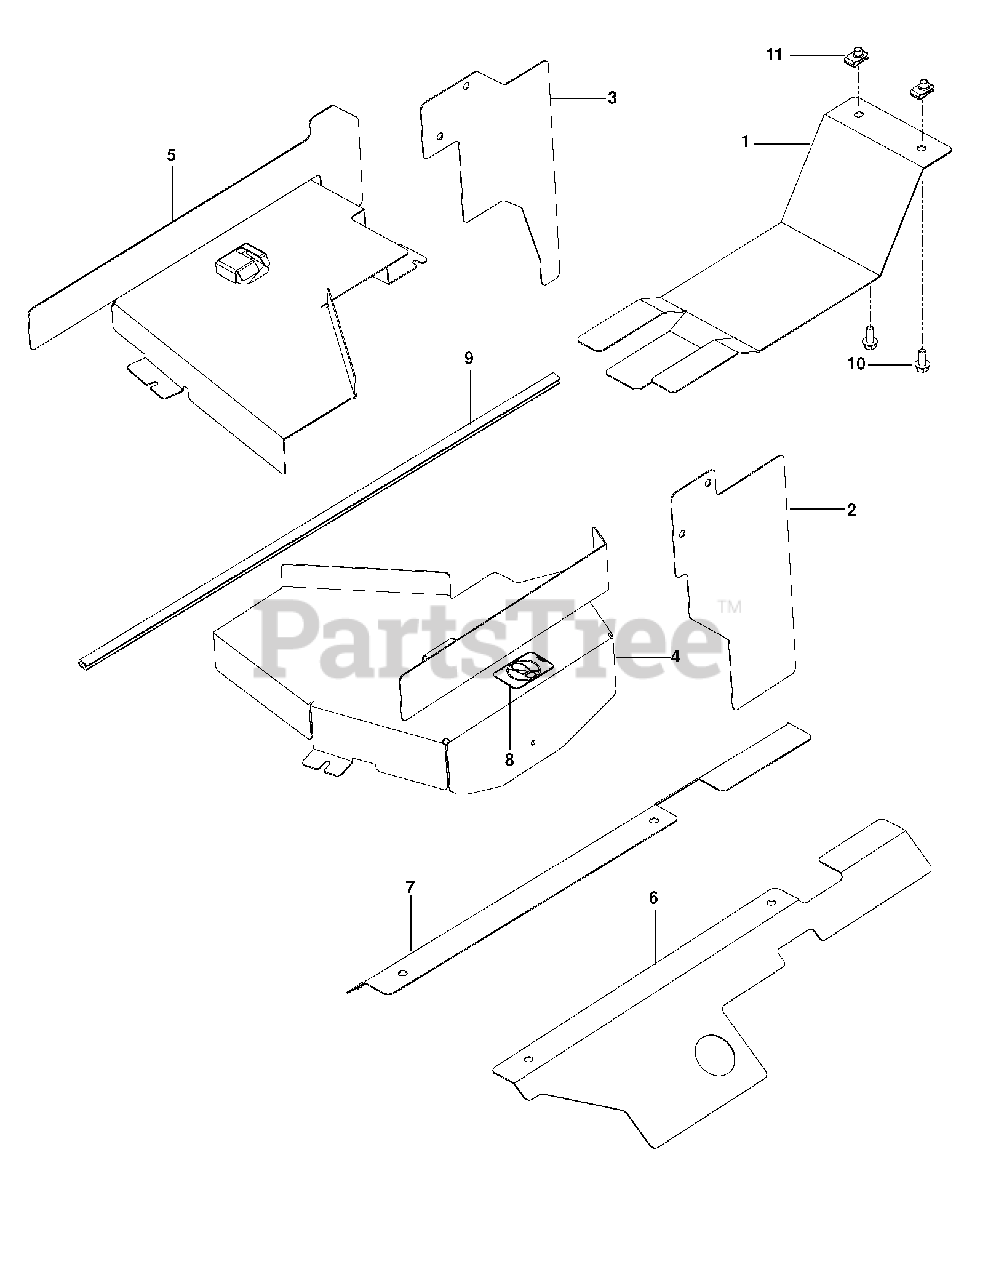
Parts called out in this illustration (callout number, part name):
1	GUARD REAR
2	GUARD FLAT WALL LT
3	GUARD FLAT WALL RT
4	GUARD BELT COVER LT
5	GUARD BELT COVER RT
6	GUARD ANGLE WALL LT
7	GUARD ANGLED WALL RT
10	HHFS 5/16-18 X 3/4
11	U-CLIP 5/16-18 NUT RETAINER
